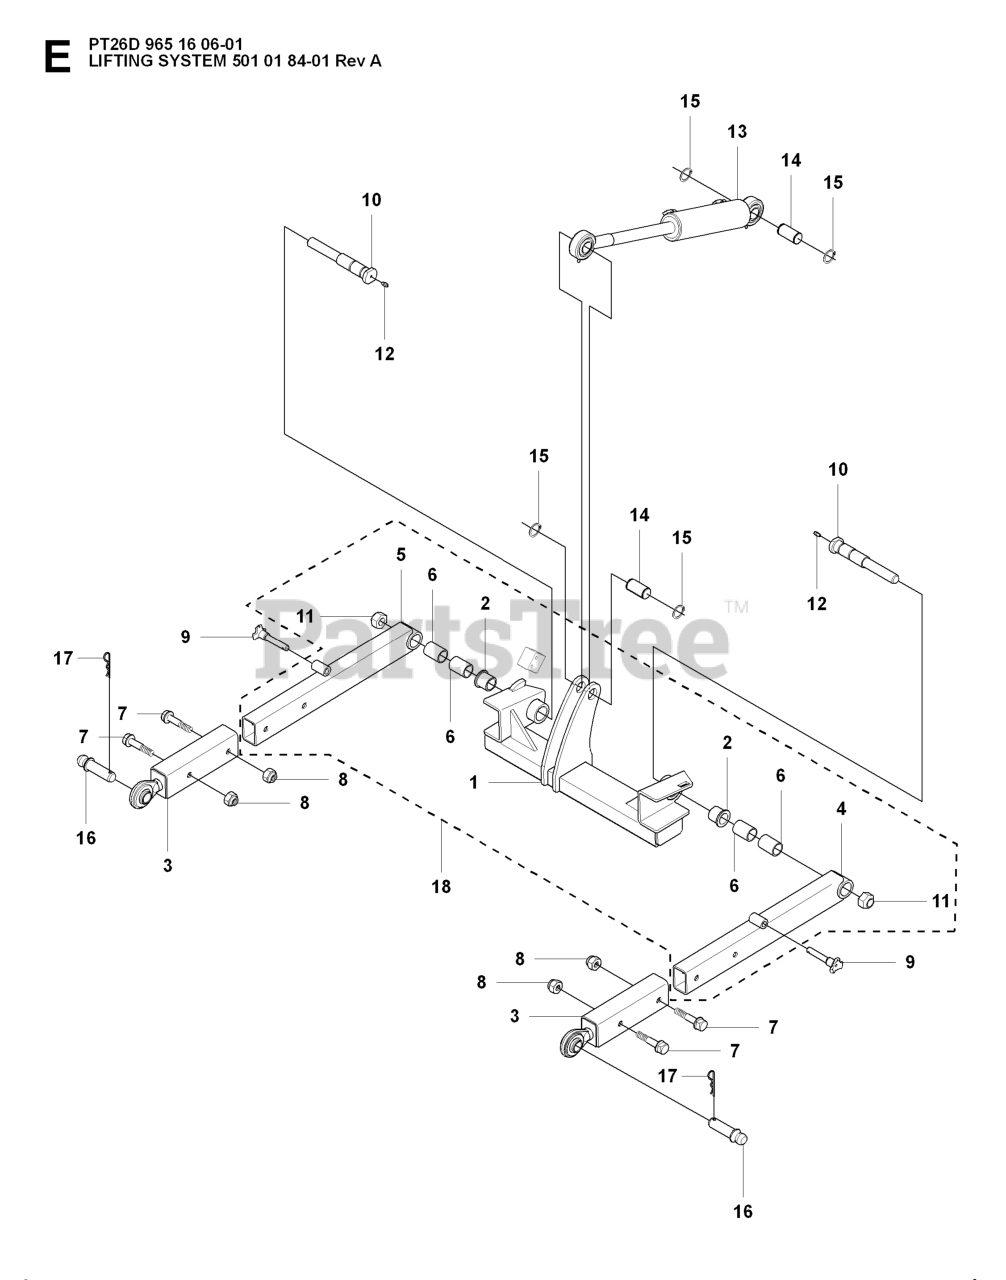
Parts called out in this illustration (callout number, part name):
1	BEAM PACKING BEAM
3	EQUIPMENT FRAME
4	LIFTING ARM LEFT
5	LIFTING ARM RIGHT
6	BEARING BUSHING
11	NUT LOCKING
12	GREASE NIPPLE
13	HYDRAULIC CYLINDER
15	RETAINING RING SGA 25
16	BOLT LIFTING ARM
